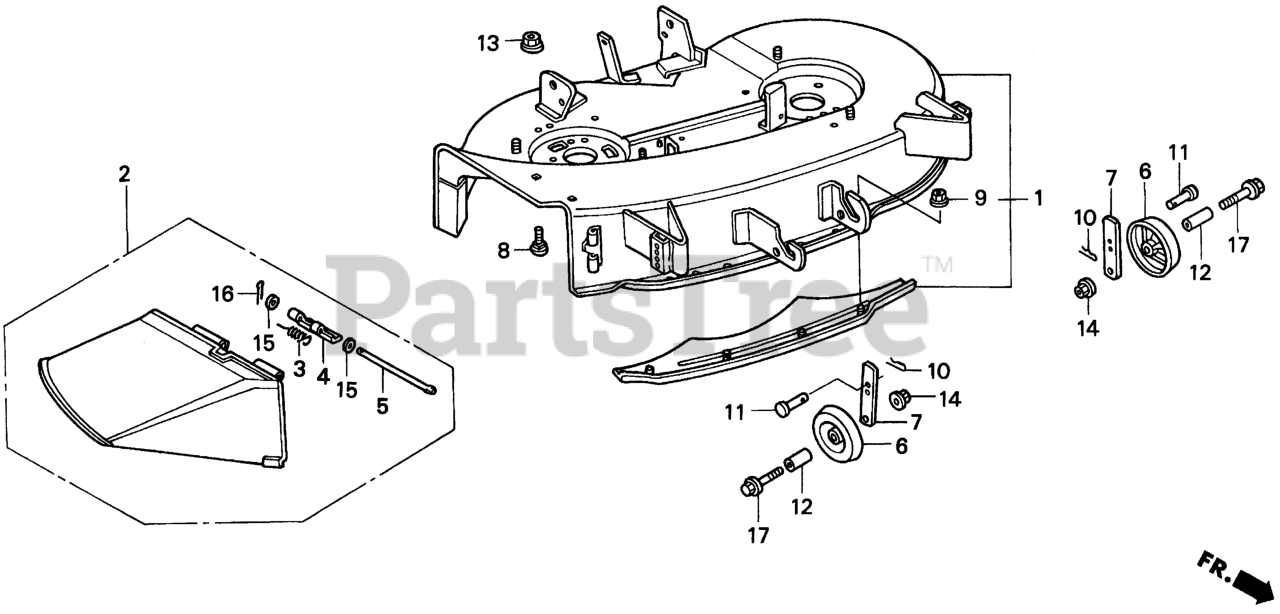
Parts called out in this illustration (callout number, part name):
1	HOUSING, CUTTER
2	ADAPTER, DISCHARGE
3	SPRING, DISCHARGE ADAPTER
4	HINGE, DISCHARGE ADAPTER
5	PIN, DISCHARGE ADAPTER (NA USE ALT:06814-V09-A01)
6	ROLLER, ANTI-SCALP
7	ARM, ROLLER
8	BOLT, SPECIAL (9X15)
9	NUT, FLANGE (8MM)
10	PIN, SNAP (7MM)
11	PIN, ROLLER ARM (8X22)
12	COLLAR, ANTI-SCALP
13	NUT, FLANGE (8MM)
14	NUT, FLANGE (10MM)
15	WASHER, PLAIN (6MM)
16	PIN, COTTER (2.0X15)
17	BOLT, FLANGE (10X65)
